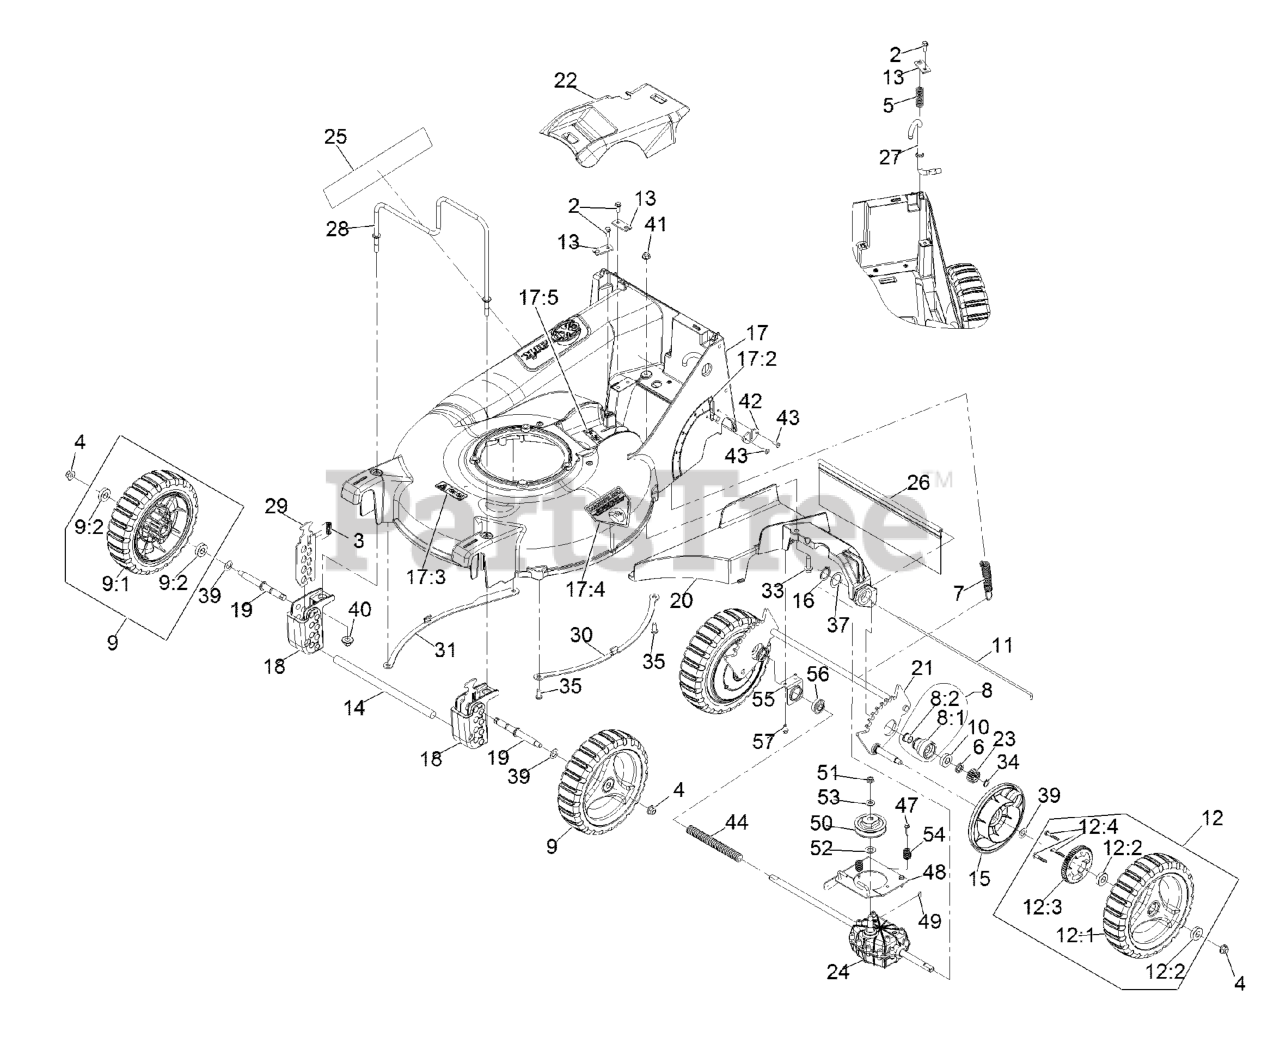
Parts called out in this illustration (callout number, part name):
2	SCREW-HWH
3	SPRING-COMPRESSION
4	NUT-HF, NI
5	SPRING-COMPRESSION
6	SPACER-BUSHING
7	SPRING-EXTENSION
8	HOUSING ASM
8:1	HOUSING-BEARING
8:2	BEARING-FLANGE
9	WHEEL ASM, 9" W/BEARINGS
9:1	WHEEL ASM, 9"
9:2	BEARING-BALL
10	BEARING-BALL
11	ROD,SHIELD
12	WHEEL ASM, 9 W/GEAR
12:1	WHEEL ASM, 9"
12:2	BEARING-BALL
12:3	GEAR-WHEEL, 52T
12:4	STUD-DRIVE
13	BRACKET,MOUNT
14	ROD,BUMPER
15	COVER,GEAR
16	RING-RETAINING
17	DECK W/DECALS
17:2	DECAL-HEIGHT OF CUT
17:3	DECAL-WARNING, BLADE
17:4	DECAL-DANGER
17:5	DECAL-DANGER
18	BLOCK,FRONT QUADRANT
19	AXLE-WHEEL
20	BRACKET-TRANSMISSION AND
21	WLD,REAR AXLE P21
22	COVER,BELT
23	GEAR-PINION, 15T
24	TRANSMISSION-HD, 4.5/1
25	DECAL-COMM 21 X-SERIES
26	SHIELD-TRAILING P21
27	ROD-HEIGHT ADJ P21
28	GUARD,ENGINE
29	PLATE, FRONT HEIGHT
33	SCREW-HWHTF
34	RING-RETAINING
35	SCREW-BHTF
39	WASHER-PLAIN
40	Nut-Nyloc 3/8-16 Flg
41	NUT-HF, NI
42	PLATE,WEAR
43	RIVET-BLIND
44	COVER-SHAFT-DRIVE
47	SCREW-SPECIAL
48	TRANSMISSION PLATE ASM
49	KEY-WOODRUFF
51	NUT-HEX
52	WASHER-THRUST
53	WASHER-FLAT
54	SPRING,COMPRESSION
55	MOUNT-BEARING
56	BEARING-BALL
57	SCREW-HWH
